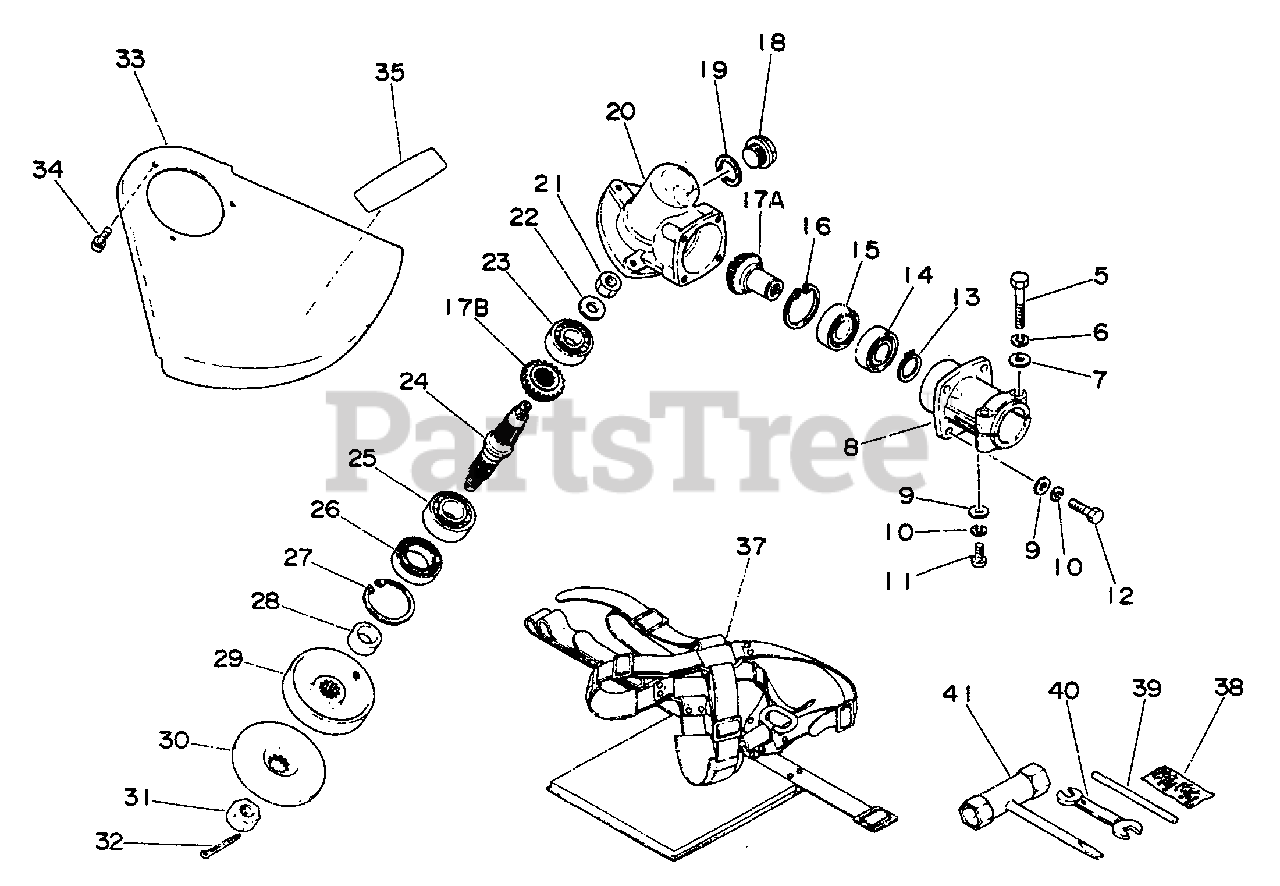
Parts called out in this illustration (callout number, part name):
5	BOLT - 6×32
6	WASHER, SPRING 6
7	WASHER 6.5×11.5×0.8
8	HOUSING, BEARING
9	WASHER, FLAT 5.5×10×0.8
10	WASHER, SPRING 5
11	SCREW 5×12
12	BOLT - 5×20
13	RING, RETAINING 15
14	BEARING, BALL 6002D
15	BEARING, BALL 6002
16	RING, SNAP Ø32
18	FITTING, GREASE
19	GASING, GEAR
20	HOUSING, GEAR CASE
21	NUT 8×1.25
22	WASHER 8.5×16×1.2
23	BEARING, BALL - 6201 C3
24	GEAR, SHAFT
25	BEARING, BALL 6202
26	SEAL
27	RING, SNAP 35
29	PLATE
30	PLATE, ADAPTER - LOWER
32	PIN, COTTER 2×22
33	SHIELD
34	SCREW 5×14
35	LABEL - ECHO
37	SHOULDER STRAP ASSY
38	PIN, COTTER 2×22 (PKG. OF 10)
39	TOOL, LOCKING 5×120 MM
40	SPANNER 8×10
41	T-WRENCH
